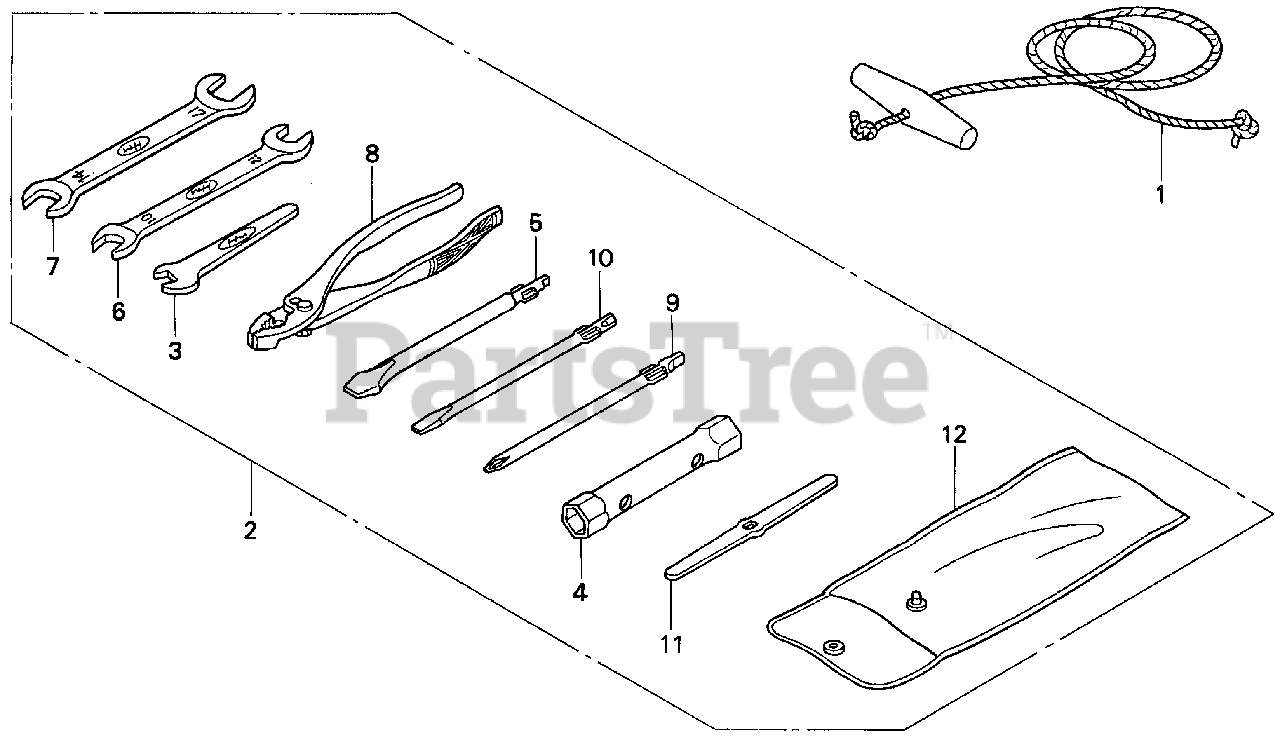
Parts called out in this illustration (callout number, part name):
1	ROPE, STARTER (#5X55")
3	WRENCH (8MM) (OPEN END) (NOT AVAILABLE)
4	WRENCH, PLUG
5	SCREWDRIVER, CHECK BOLT
6	WRENCH (10X12) (OPEN END)
7	WRENCH (14X17) (OPEN END)
8	PLIERS (135MM)
9	SCREWDRIVER 1, PHILLIPS (NO.2)
10	SCREWDRIVER 3, STRAIGHT SLOT (NO.2)
11	LEVER, TIRE
